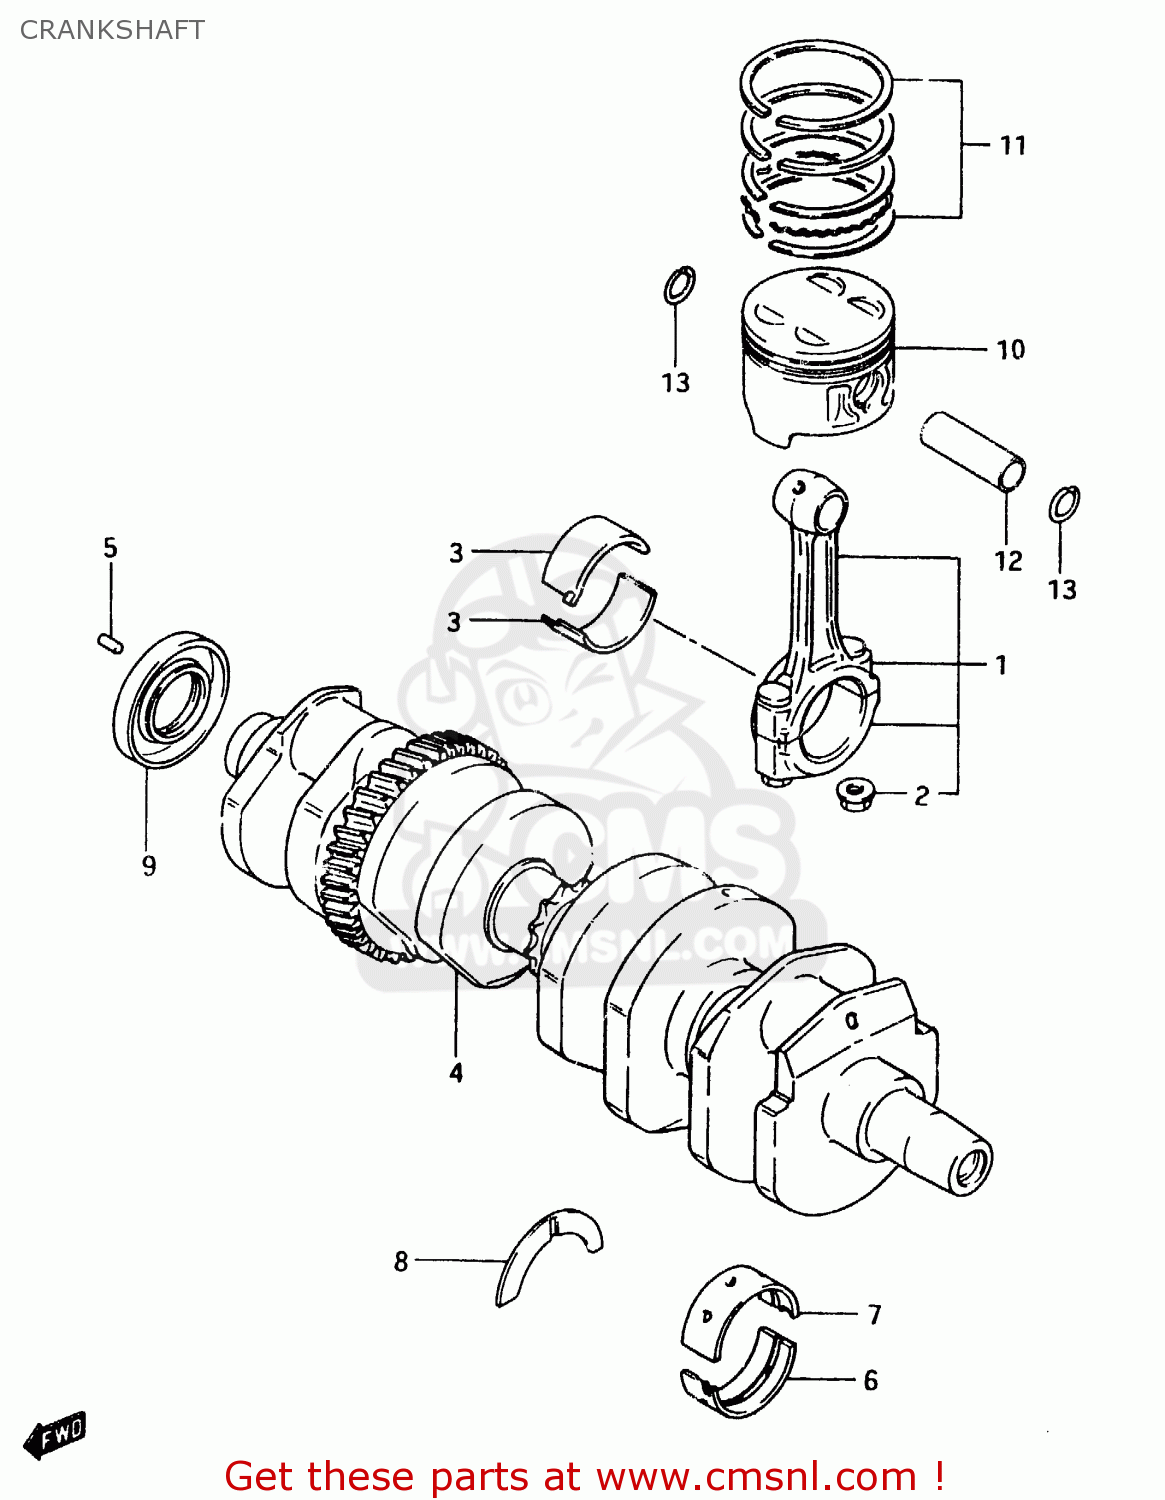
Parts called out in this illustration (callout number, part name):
1	ROD ASSEMBLY,CONNECTING
2	NUT
3	METAL,CRANK PIN
4	CRANKSHAFT ASSEMBLY
5	PIN
6	METAL,CRANKSHAFT (GREEN)
7	METAL CRANKSHAFT (GREEN)
8	PLATE,CRANK THRUST
9	OIL SEAL
10	PISTON
11	RING SET,PISTON
12	PIN,PISTON
13	CIRCLIP,PISTON PIN
